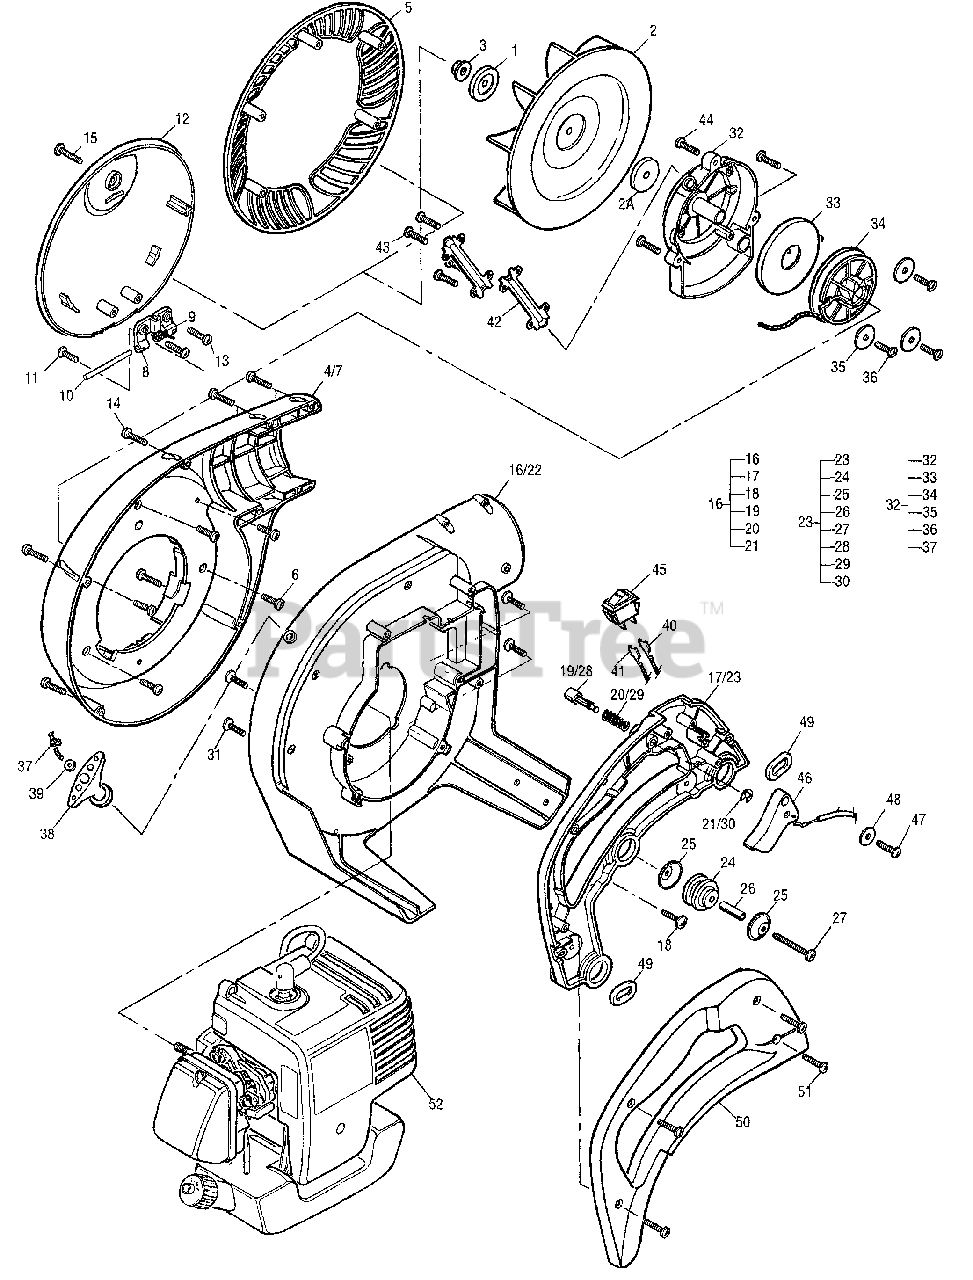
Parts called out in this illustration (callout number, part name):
1	Disc Drive
2	Kit, Impellar, Blower/Vac
2A	Disc Drive
3	Nut, Hx 5/16-24
4	Outer Housing (Yellow)
4	Outer Housing (Grey)
5	Cover, Impellar (Yellow)
5	Cover, Impellar (Grey)
6	Screw, 8-16 x .75 Tr Hd Plastite
7	Outer Housing, Blo/Vac (Yellow)
7	Outer Housing, Blo/Vac (Grey)
8	Hinge
9	Spring, Torsional
10	Pin, Cover
11	Screw, 10-14 x .625 Plastite
12	Cover, Fan (Yellow)
12	Cover, Fan (Grey)
13	Screw, 8-16 x .75 Tr Hd Plastite
14	Screw, 8-16 x .75 Tr Hd Plastite
15	Screw, 10-24 x .875 Taptite
16	Kit, Inner Housing, Non-AV
17	Handle, Left
18	Screw, 10-14 x .75 Tr Torx
19	Lock, Throttle
20	Spring, Compression
21	Ring, Retaining
22	Inner Housing Asy, AV
23	Left Handle, AV
24	Isolator Rubber
25	Washer, Isolator
26	Spacer, .21 ID x 1.00 Long
27	Screw, 10-24 x 1.75 Tr Hd Torx
28	Throttle Lock
29	Spring, Compression
30	Ring, Retaining
31	Screw, 10-24 x .63 SI Torx Tp
32	Kit, Starter Housing Asy
33	Spring/Starter Rewind
34	Pulley, Starter
35	Washer, .2 ID x 718 in. OD
36	Screw, 8-16 x .75 Tr Hd Plastite
37	Rope, Starter 46"
38	Handle Starter
39	Washer, Nylon
40	Wire Asy, Ground
41	Wire Asy, Stop Switch
42	Cover, Rope
43	Screw, 8-16 x .75 Tr Hd Plastite
44	Screw, 8-16 x .75 Tr Hd Plastite
45	Momentary Switch
46	Throttle Trigger
47	Screw, 8-16 x .75 Tr Hd Plastite
48	Washer, .19 ID x .68 OD
49	Harness Link
50	Handle, Right
51	Screw, 8-16 x .75 Tr Hd Plastite
52	Powerhead Asy
